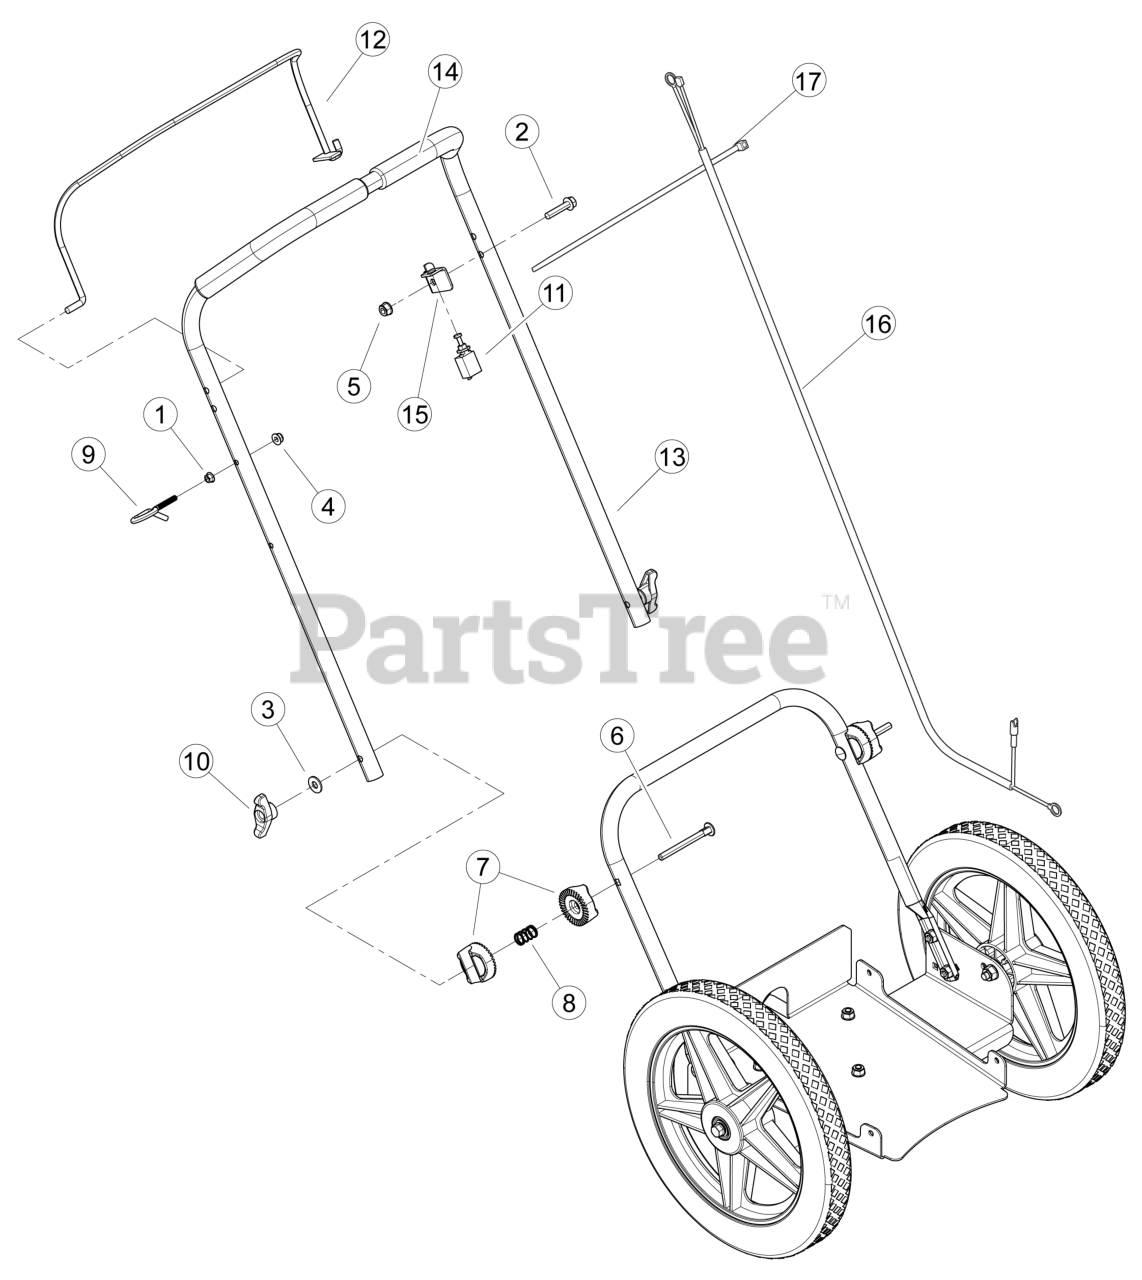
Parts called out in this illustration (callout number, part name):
1	NUT, 1/4"-20 SERRATED FLANGE NC ZP
2	BOLT, 5/16 × 1-1/2 FLANGE NC
3	WASHER, 5/16 FLAT
4	NUT, 1/4-20 NYLOCK-FLANGE
5	NUT, 5/16-18 NYLOCK FLANGE
6	BOLT, 5/16-18 × 3-1/2 LONG NECK GR5 CRG ZP
7	RETAINER, HANDLE BAR ADJUSTMENT
8	SPRING, RETAINER COMPRESSION
9	GUIDE, RECOIL ROPE
10	KNOB, 5/16-18 FEEM TEE
11	SWITCH, ENGINE KILL
12	ASSEMBLY, BAIL HW TRIMMERS
13	ASSEMBLY, UPPER HANDLE BAR WITH GRIPS
14	PAD, FOAM HANDLE BAR
15	BRACKET, HW KILL SWITCH
16	HARNESS, BRIGGS HW KILL SWITCH
17	STRAP, 11 IN BLACK TIE
